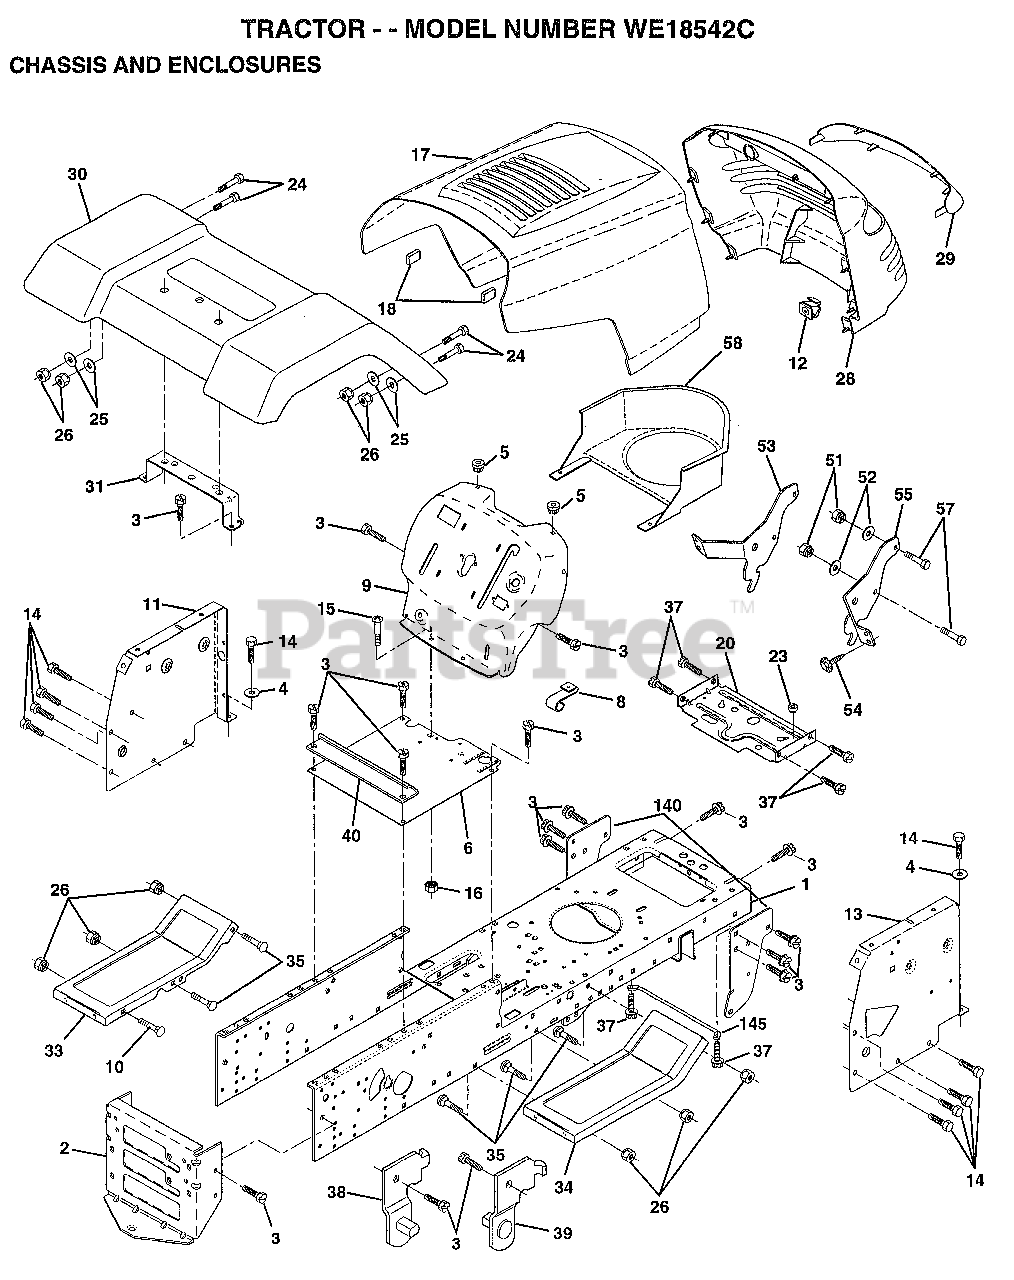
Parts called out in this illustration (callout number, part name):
3	SCREW
4	WASHER
5	BUMPER-HOOD/DASH
6	SADDLE
8	CLIP.RETAINER
9	DASH SILKSCREEN
11	"PANEL-DASH,LH"
12	CLIP.TINNERMAN
14	SCREW LT
15	SCREW
17	HOOD.STEEL.ASSY
20	"PLATE-MTG,BATT/FU"
24	BOLT
25	WASHER
26	NUT
28	GRILLE-MS428
29	LENS GRILLE
31	BRACKET SUPT FEND
33	FOOTREST.LH.LT/GT
34	FOOTREST.RH.LT/GT
35	BOLT
38	BRACKET ASM LH
39	BRACKET ASM RH
40	SPACER FENDER LT
51	NUT
52	WASHER
53	BRACKET.GRILLE.LH
54	SCREW.HEX.WS.HD
55	BRACKET.GRILLE.RH
58	DUCT.AIR.B&S.18HP
140	BRKT SUSPENSION
145	"ROD POVOT,CHASSIS"
